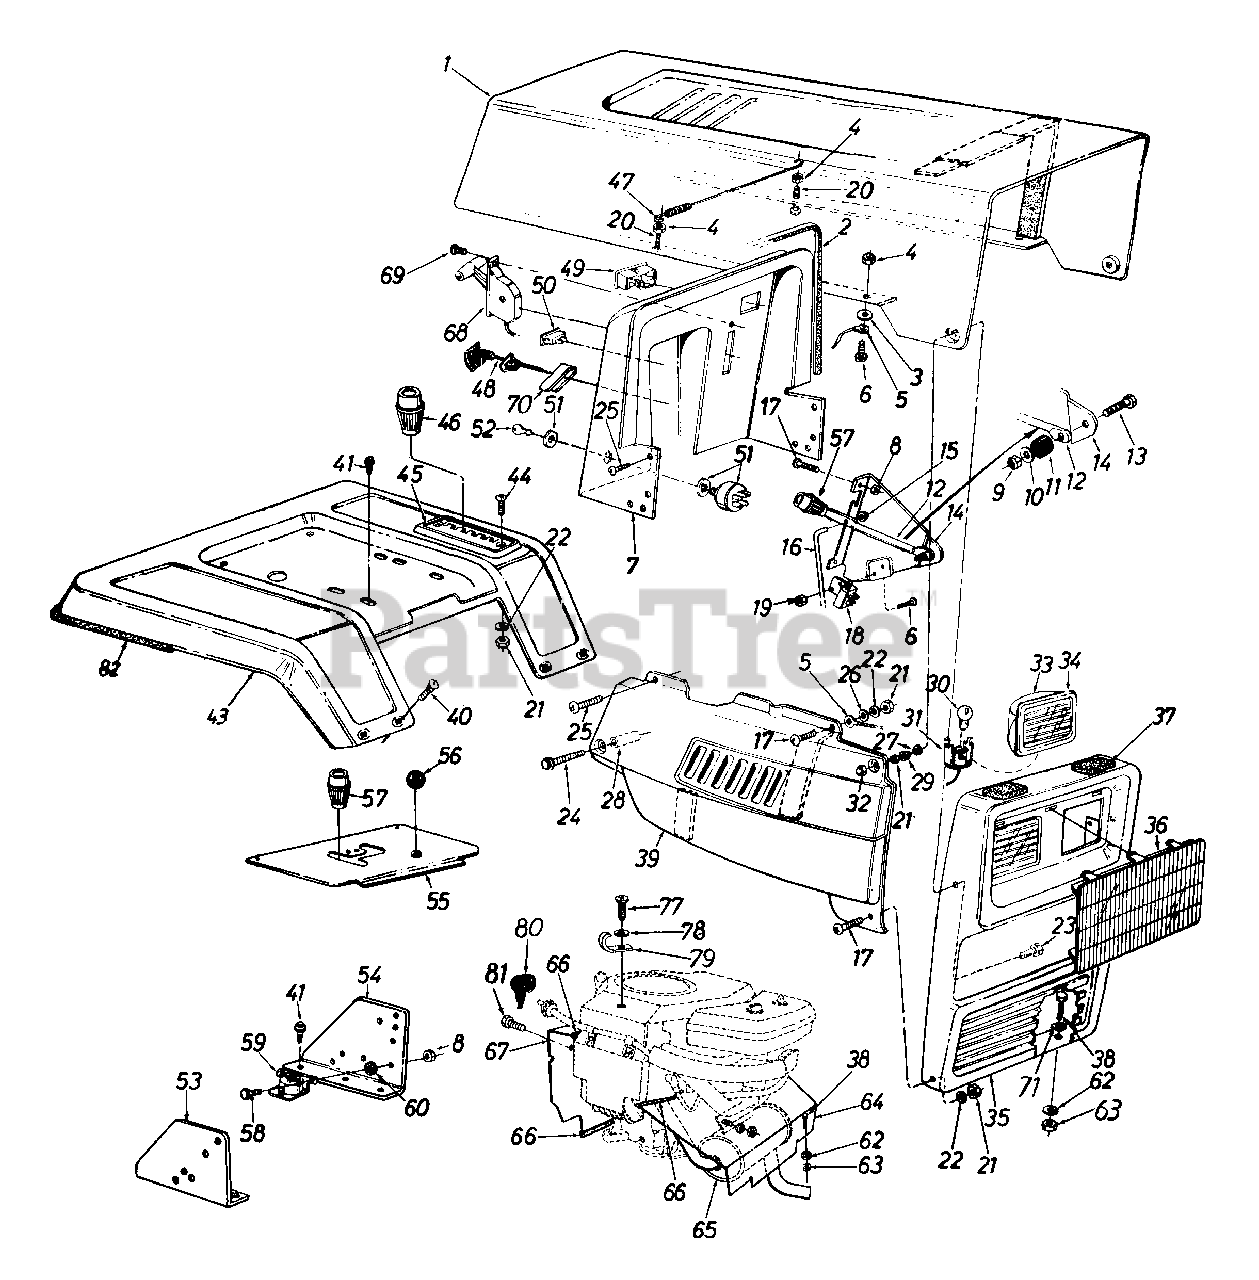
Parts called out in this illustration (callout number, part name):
1	Hood
2	Trim Strip 31" Lg.
3	Fl-Wash. .20" I.D. x .41" O.D.
4	Hex Sems Nut #10-24 Thd.
5	Hood Stop
6	Truss Mach. Scr. #10-24 x .5" Lg.
9	Hex L-Nut 1/4-20 Thd.
10	Fl-Wash. .281" I.D. x .73" O.D.
11	Rubber Washer
12	PTO Lever
13	Hex Bolt 1/4-20 x 1.25" Lg.
14	Deck Clutch Control Brkt.
15	Push Cap
16	Deck Control Rod
17	Truss Mach. Scr. 1/4-20 x .5" Lg.
18	Safety Switch
19	Hex Sems Nut #10-24 Thd.
20	Hex Bolt 10-24 x 1.0" Lg.
21	Hex Nut 1/4-20 Thd.
22	L-Wash. 1/4" I.D.
23	Hex Bolt 1/4-20 x .88" Lg.
24	Hex Wash. TT-Tap Scr. 1/4-20 x 1.75" Lg.
25	Hex TT-Tap Scr. 1/4-20 x .75" Lg.
26	Fl-Wash. .25" I.D. x .62"
27	Spr. Wash. .39" I.D. x .62"
28	Spacer .26" I.D. x .375"
29	Shld. Spacer .375" Dia. x .125" Lg.
30	Lamp
31	Socket
32	Acorn Nut 1/4-20 Thd.
33	Headlight Housing
34	Headlight Lens
37	Foam Strip
38	Hex Bolt 5/16-18 x .75" Lg.
41	Hex Wash. AB-Tap Scr. 5/16 x .75" Lg.
45	6-Speed Selector Plate
46	Shift Knob
47	Hood Spring
48	Choke Control 46" Lg.
49	Ammeter
50	Light Switch
51	Ignition Switch
52	Ignition Key
56	Ball Knob
57	Knob - Blade Clutch
58	Hex Bolt 1/4-20 x .5" Lg.
59	Solenoid
60	Ext. L-Wash. 1/4" I.D.
62	L-Wash. 5/16" I.D.
63	Hex Nut 5/16-18 Thd.
64	Front Heat Sheild
65	Muffler
66	Trim Strip 12" Lg.
67	Rear Baffle
68	Throttle Control Box Ass'y.
69	Truss Mach. AB-Tap Scr. #10 x .5" Lg.
70	Retainer Clip
71	Fl-Wash..344" I.D. x 1" O.D. (Hdn.)
77	Truss Mach. B-Tap Scr. #10 x .5" Lg.
78	Fl-Wash. .188" I.D. x .438" O.D.
79	Clamp
81	Hex Wash Hd. TT-Tap Scr. 1/4-20 x .5" Lg.
82	Trim Strip 81" Lg.
